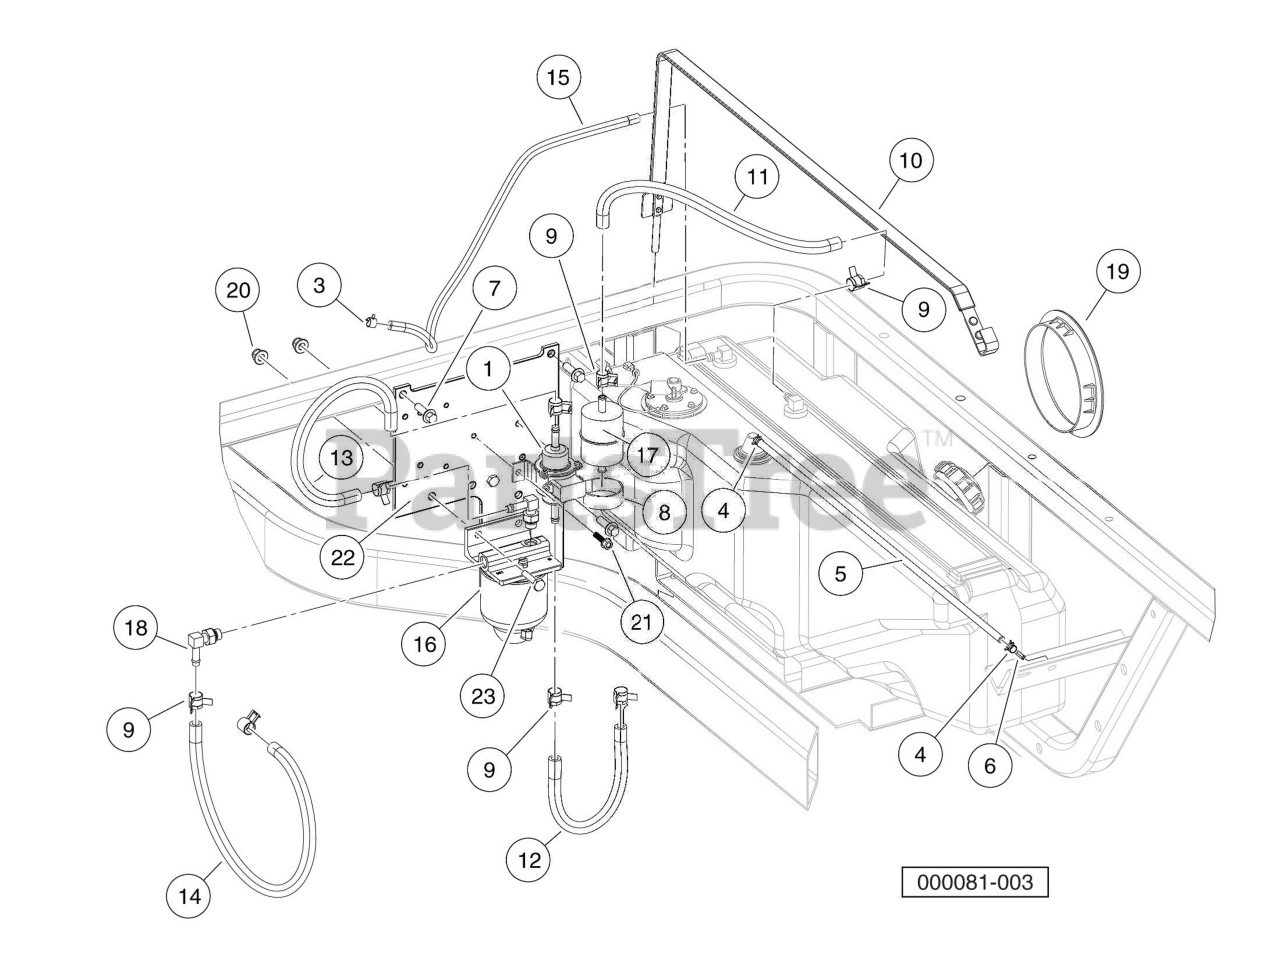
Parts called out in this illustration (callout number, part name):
1	Pump, Diesel Fuel Electric
2	Asm, Fuel System, Kubota
3	Clamp, Green Hose
4	Clamp, 0.301 ID Hose
5	Hose, Fuel, Vent, 22" Long
7	Screw, M8X1.25X30, Hex
8	P-Clamp, Insulated 1.75 In
9	Clamp, Hose, Ctb 14mm
10	Strap, Tank, Fuel
11	Hose, Tank To Prefilter Diesel
12	Hose, Fuel Prefilter To Pump
13	Hose, Fuel Pump To Filter
14	Hose, Fuel Filter To Eng
15	Hose, Fuel Return
16	Filter Assy, Fuel
17	Filter, Fuel.
18	Adapter, 90, 5/16 Tube
19	Bezel, Fuel Fill.
20	Lock Nut, Flg M8 X 1.25 Nylon
21	Screw, M6 X 1 X 25 Thd Form
22	Plate, Fuel/Oil System
23	Bolt, M8 X 1.25 X 30
